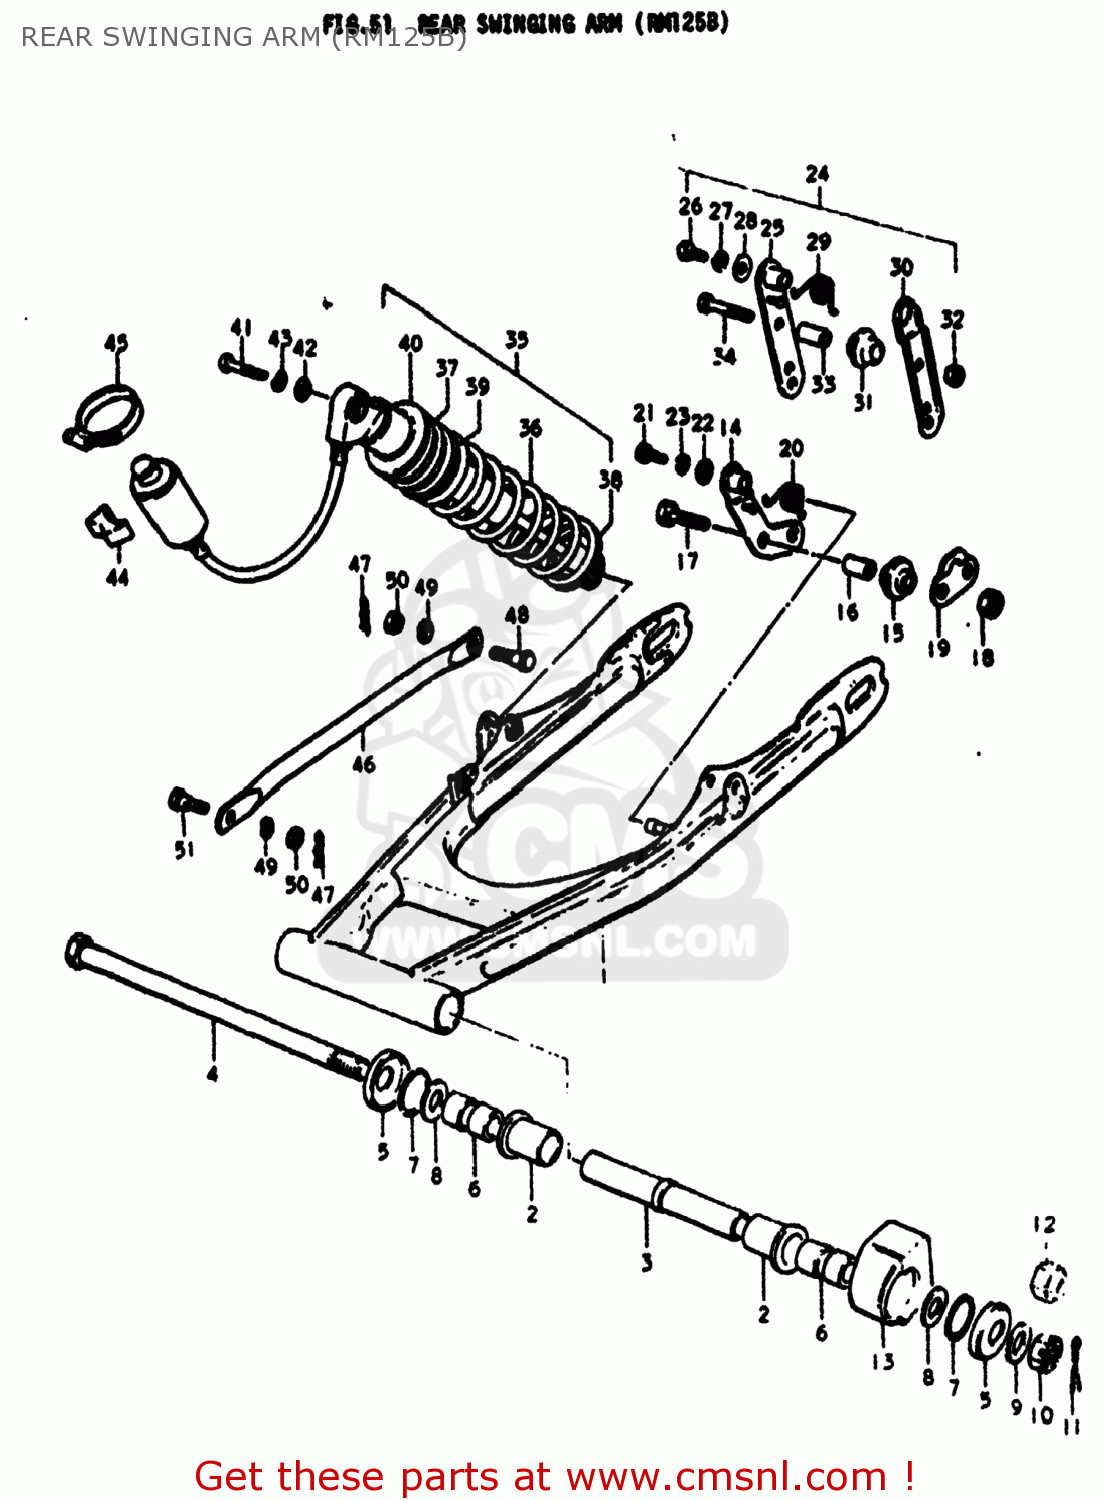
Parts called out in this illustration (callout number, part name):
1	SWING ARM ASSEMBLY,REAR
2	BUSH
3	SPACER,SWING ARM,CENTER
4	SHAFT,REAR SWING ARM
5	COVER,SWGARM BUSH DUST SEAL
6	SPACER,RR SWGARM PIVOT
7	O RING(D:2,ID:24.5)
8	WASHER(12.5X24X2.3)
9	WASHER
10	NUT, REAR AXLE
11	PIN 30X20
12	NUT 12MM
13	BUFFER,CHAIN TOUCH DEFLECTOR
14	TENSIONER,CHAIN
15	RUBBER,CHAIN GUARD
16	SPACER(6.5X10.5X22.5)
17	BOLT
18	NUT 6MM
19	PLATE,CHAIN TENSIONER
20	SPRING
21	BOLT
22	WASHER
23	LOCK WASHER
25	TENSIONER,CHAIN
26	BOLT
27	LOCK WASHER
28	WASHER
29	SPRING
30	PLATE,CHAIN TENSIONER
31	RUBBER,CHAIN GUARD
32	NUT 6MM
33	SPACER(6.5X10.5X22.5)
34	BOLT
35	ABSORBER ASSEMBLY,REAR SHOCK
36	SPRING
37	SPRING
39	SPRING
40	GUIDE,SPRING
41	BOLT 10X40
42	WASHER
43	LOCK WASHER
44	CUSHION,RR SHOCK ABSORBER
45	CLAMP
46	TORQUE LINK,REAR
47	CLIP
48	BOLT(8X26.5)
49	LOCK WASHER
50	NUT
51	BOLT(8X22)
